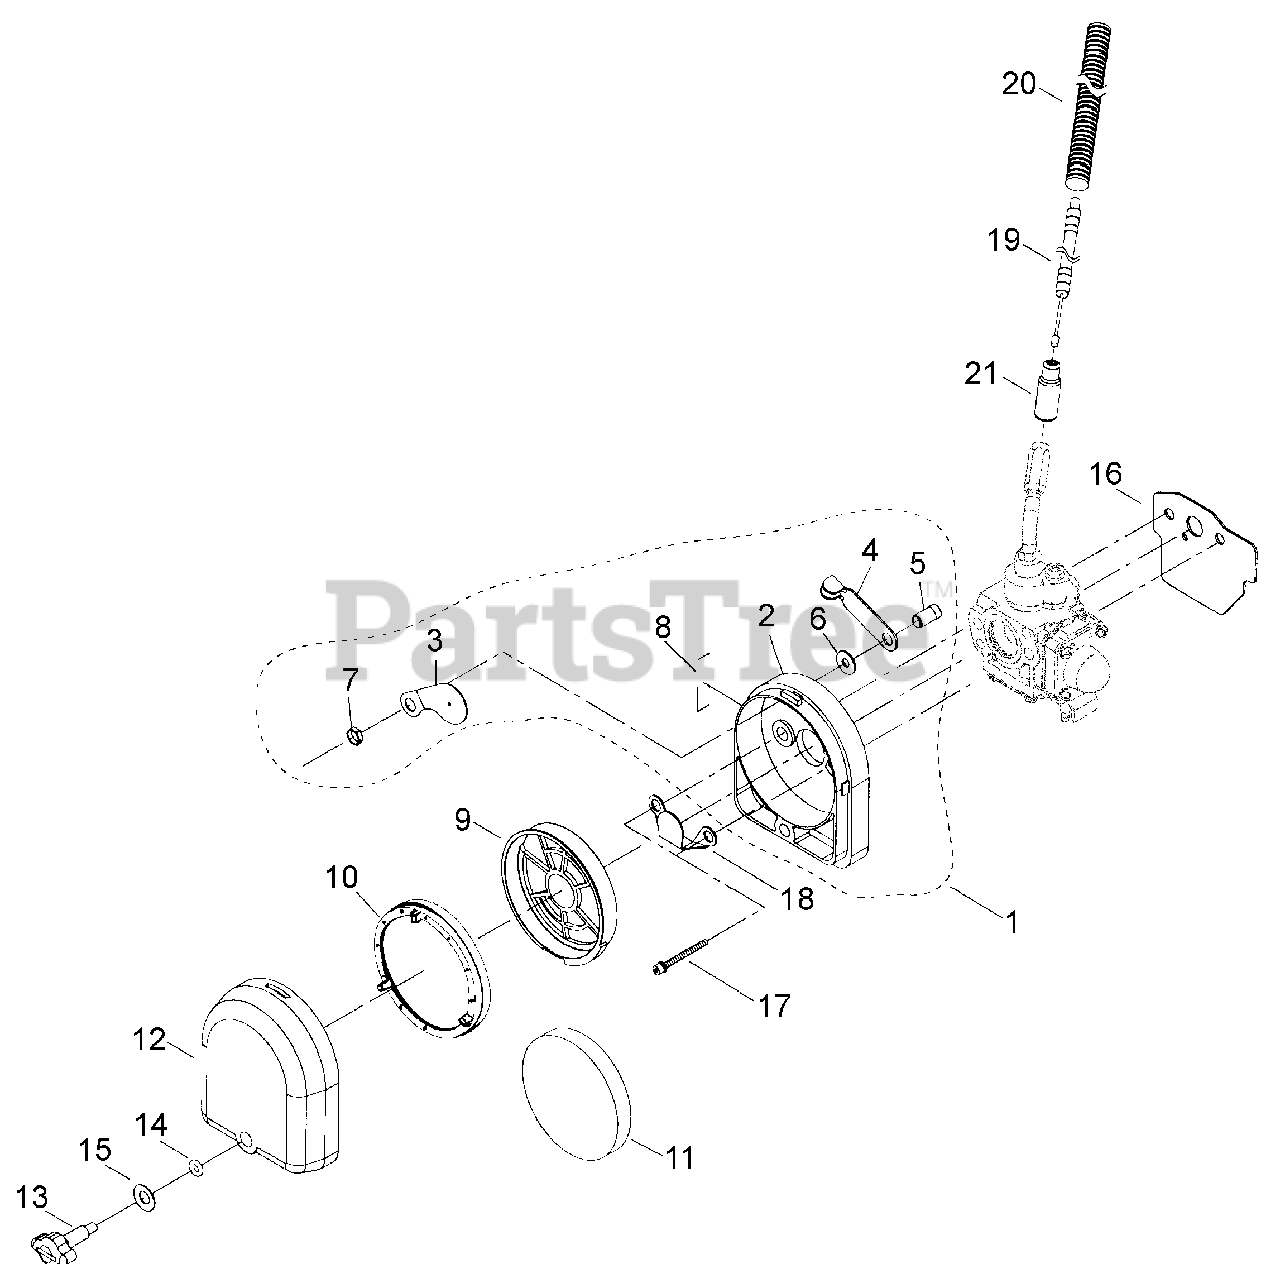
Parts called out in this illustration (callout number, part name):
1	AIR FILTER CASE ASSY
2	CLEANER BODY
3	PLATE, CHOKE
4	LEVER, CHOKE
5	SHAFT, CHOKE
6	WASHER - CONICAL
7	NUT - 6
8	LABEL - CHOKE
9	NET
10	FILTER, AIR - HEAVY DUTY
11	FILTER, AIR - FOAM
12	CLEANER COVER
13	THUMBSCREW
14	O-RING
15	WASHER - CONICAL
16	GASKET, CABURETOR
17	SCREW - 5X50
18	PLATE
19	CABLE, THROTTLE
20	TUBE
21	CAP, DUST
